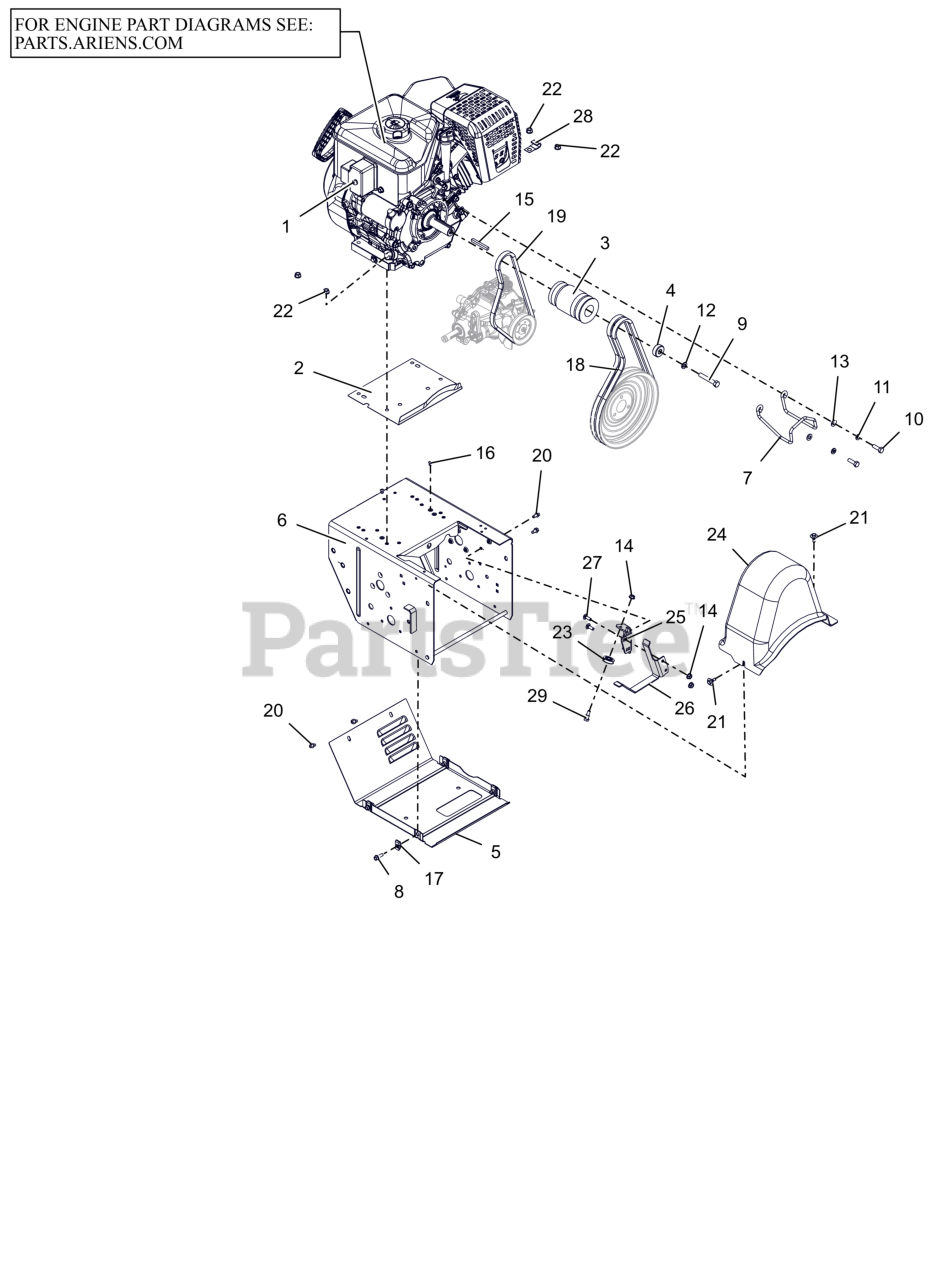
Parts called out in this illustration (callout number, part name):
1	ENGINE, EFI 420 GEN 3 240V/60W
2	BAFFLE, WATER - LARGE BLOCK
3	SHEAVE, COMBO HYDRO WHEEL 4L
4	BSHG, SPCR .406 X 1.250 X .500
5	COVER, BOTTOM - VENTILATED
6	FRAME, MAIN - PRO (WELDMENT)
7	FINGER, BELT
8	BLT, HWH .25-20X.75 G5 ZCC
9	BLT, HEX .38-24X2.25 G5 ZCC
10	BLT, HEX 0.3125-24X1 G5 ZCC
11	WSHR, LK-HVY .312X.097 ZCC
12	WSHR,LK-REG .375X.094 ZCC
13	WSHR,FLT .344X.688X.065 ZCC
14	NUT-LK-TOP-FLG .250-20 GF ZCC
15	KEY .25X.25X2.25
16	RVT, POP .1875 ZCC
17	NUT-RTNR .25-20X.56
18	V-BELT, HA-RAW EDGE (SET)
19	V-BELT, 4L-WRAPPED
20	SCR-TAP .25-20X.50 HWH ZCC
21	SCR-TAP .25-20X.5 CAPTIVE
22	NUT,LK-CTR-FLG .31-18 GF ZCC
23	PULLEY, CABLE
24	COVER, BELT-LARGE
25	BRACKET, CLUTCH CABLE
26	FINGER, BELT - FLAT
27	BLT, RHSN .25-20X.750 G5 ZCC
28	J-CLAMP
29	BOLT, SHLDR -.375 X .375 X .25-20
